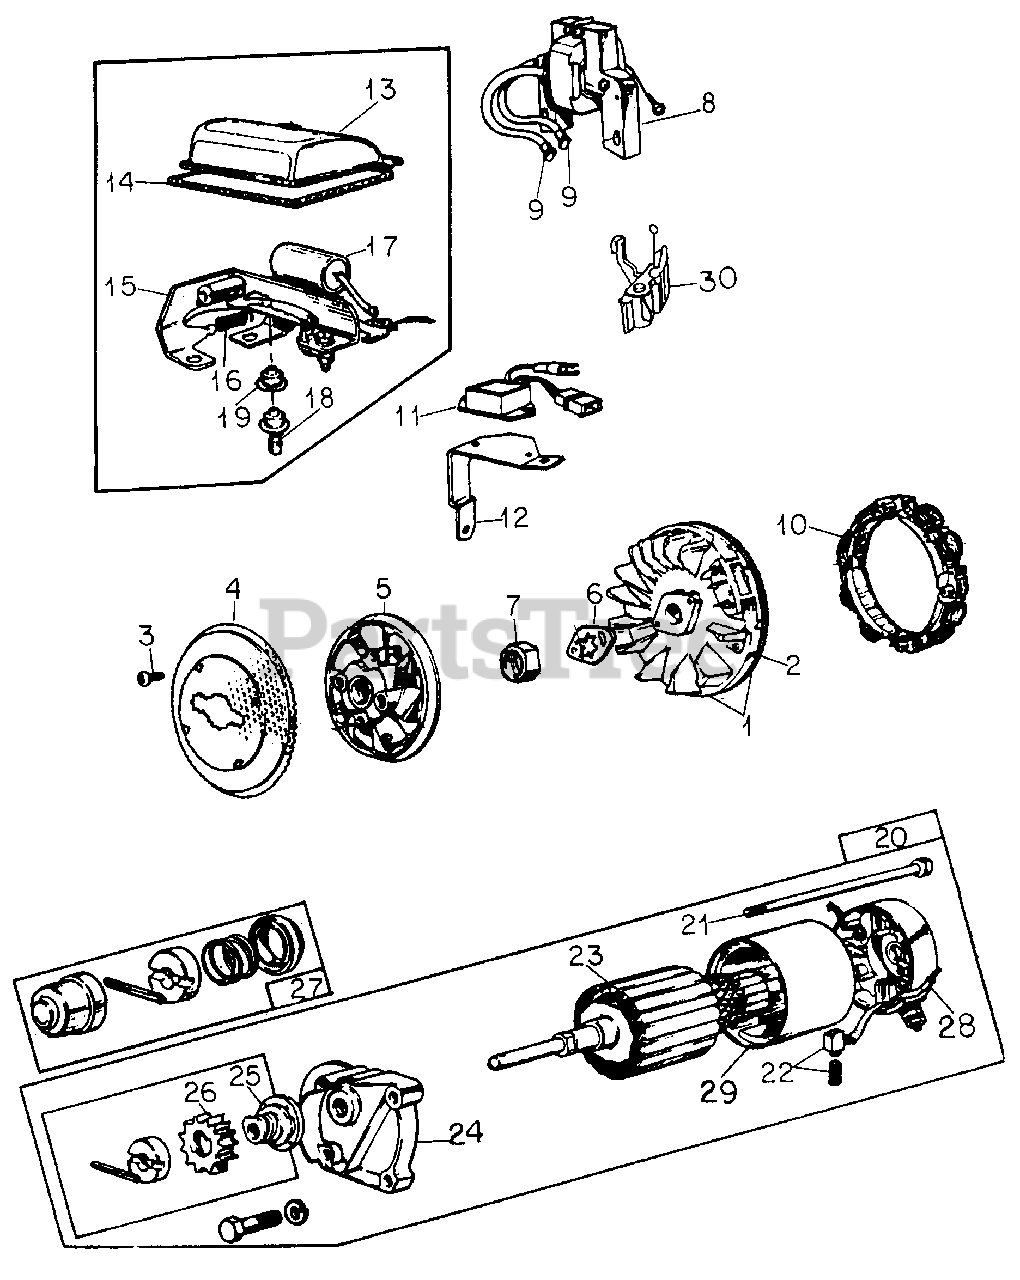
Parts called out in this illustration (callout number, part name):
1	Flywheel w/Ring Gear Assy
2	Gear, Flywheel Ring
3	Screw, Flywheel Screen
4	Screw, Flywheel
5	Fan, Booster
6	Lock, Flywheel
7	Nut, Flywheel
8	Armature Assy
8	Armature Assy, Magnetron Ignition
9	Terminal, Mag. Cable
10	Stator, Alternator
11	Regulator, Alternator
12	Bracket, Regulator Mounting
13	Cover, Breaker Points
14	Gasket, Cover
15	Breaker Assy, Ignition Points
16	Spring, Ignition Points
17	Condenser
18	Plunger, Breaker Points
19	Seal, Plunger
20	Motor, Starter
21	Bolt, Thru
22	Set, Brush
23	Armature Assy
24	Cap Assy, Drive End
25	Clutch Assy, Starter
26	Gear, Starter
27	Kit, Pinion Spring
28	Cap Assy, Commutator End
29	Housing, Starter
30	Coil Assy, Trigger
